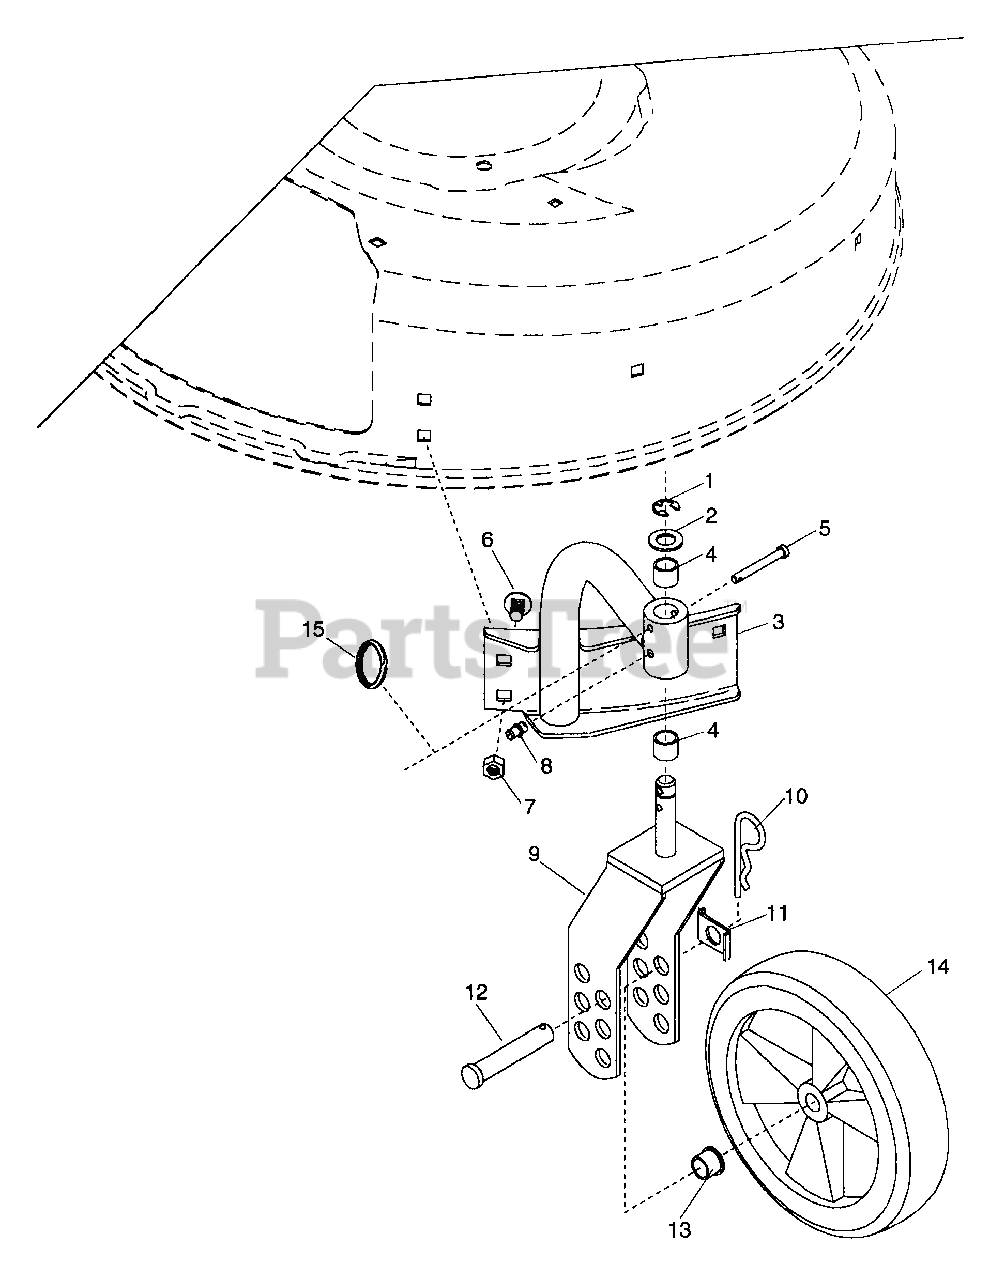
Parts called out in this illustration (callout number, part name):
1	RG-RTNG-EXT .625X.042
2	WSHR-FL-STL .630X1.005X.062 PL
3	RIGHT MOUNT ARM WELDMENT
4	BSHG-SLV .625X.750X.500 BR
5	PIN-CLEV .25X1.75
6	BLT-RDHDSQSHNK .31-18X.50 YZ
7	NUT-FLG. .312-18 PL
8	FTG-LUBE .25-28X.256 YWZC
9	WHEEL YOKE WELDMENT
10	PIN-HAIR INT .14X.4X2.75
11	AXLE TAB
12	PIN-CLEV .494X2.62 YWZC
13	BSHG-FLG .500X.625X.500X.750
14	WHEEL
15	KICKOUT RING YWZC
